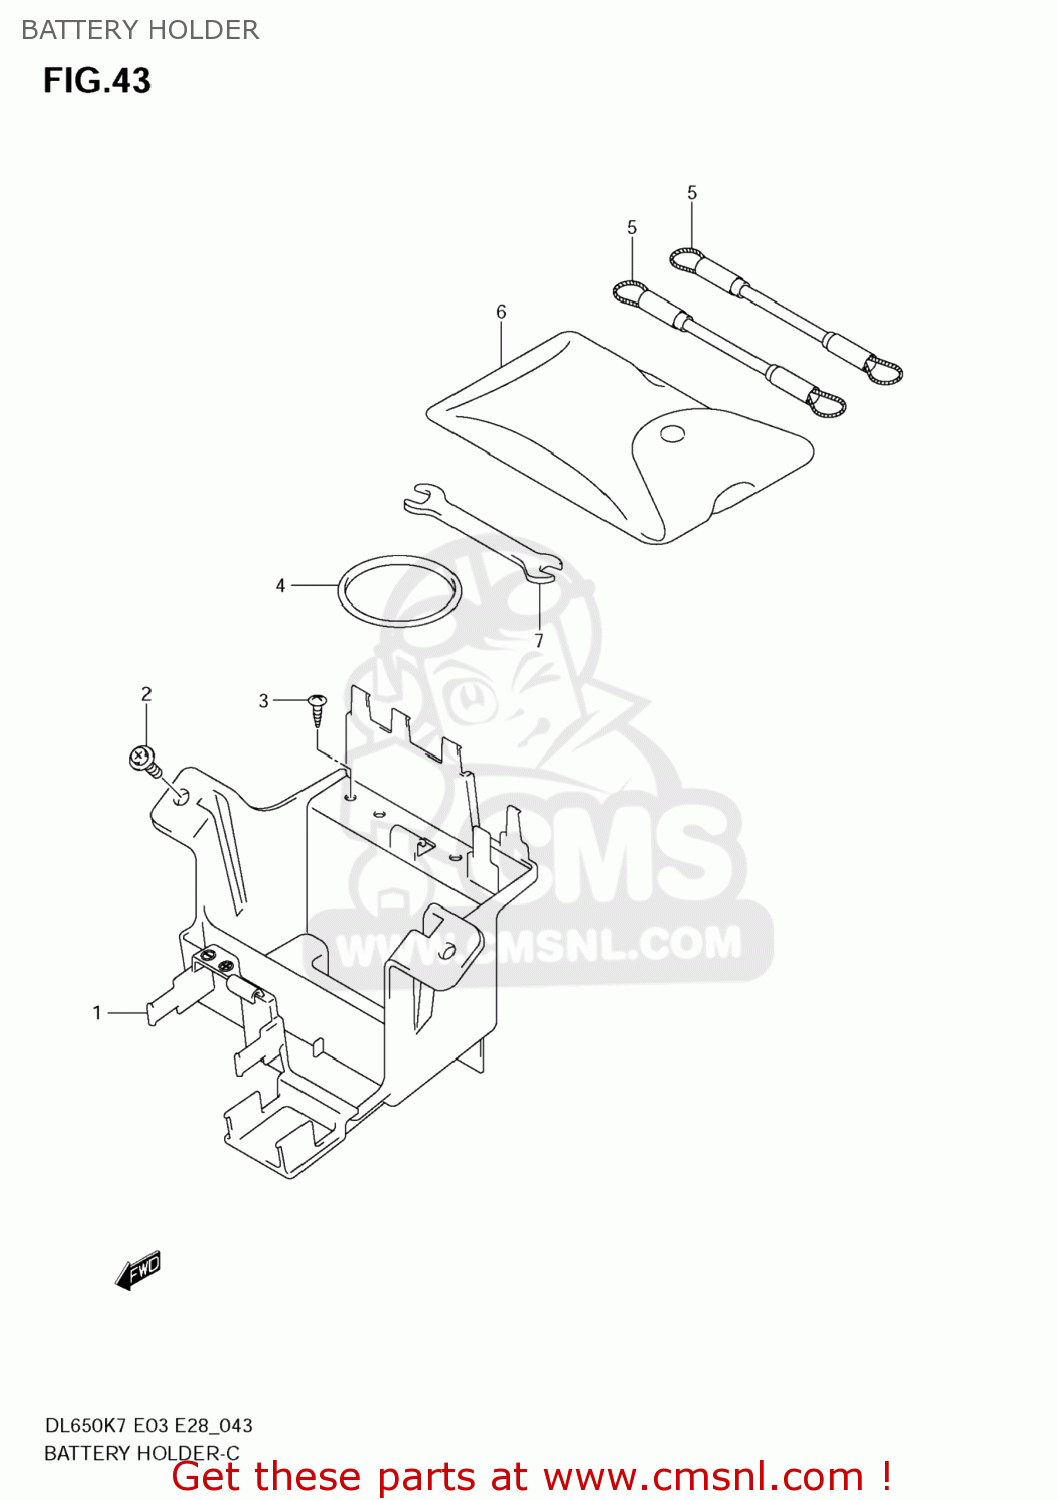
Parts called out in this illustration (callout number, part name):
1	HOLDER,BATTERY
2	BOLT
3	SCREW
4	O RING(D:3.5,ID:61)
5	CABLE,HELMET LOCK
6	TOOL ASSY
7	OPEN SPANNER(8X10)
